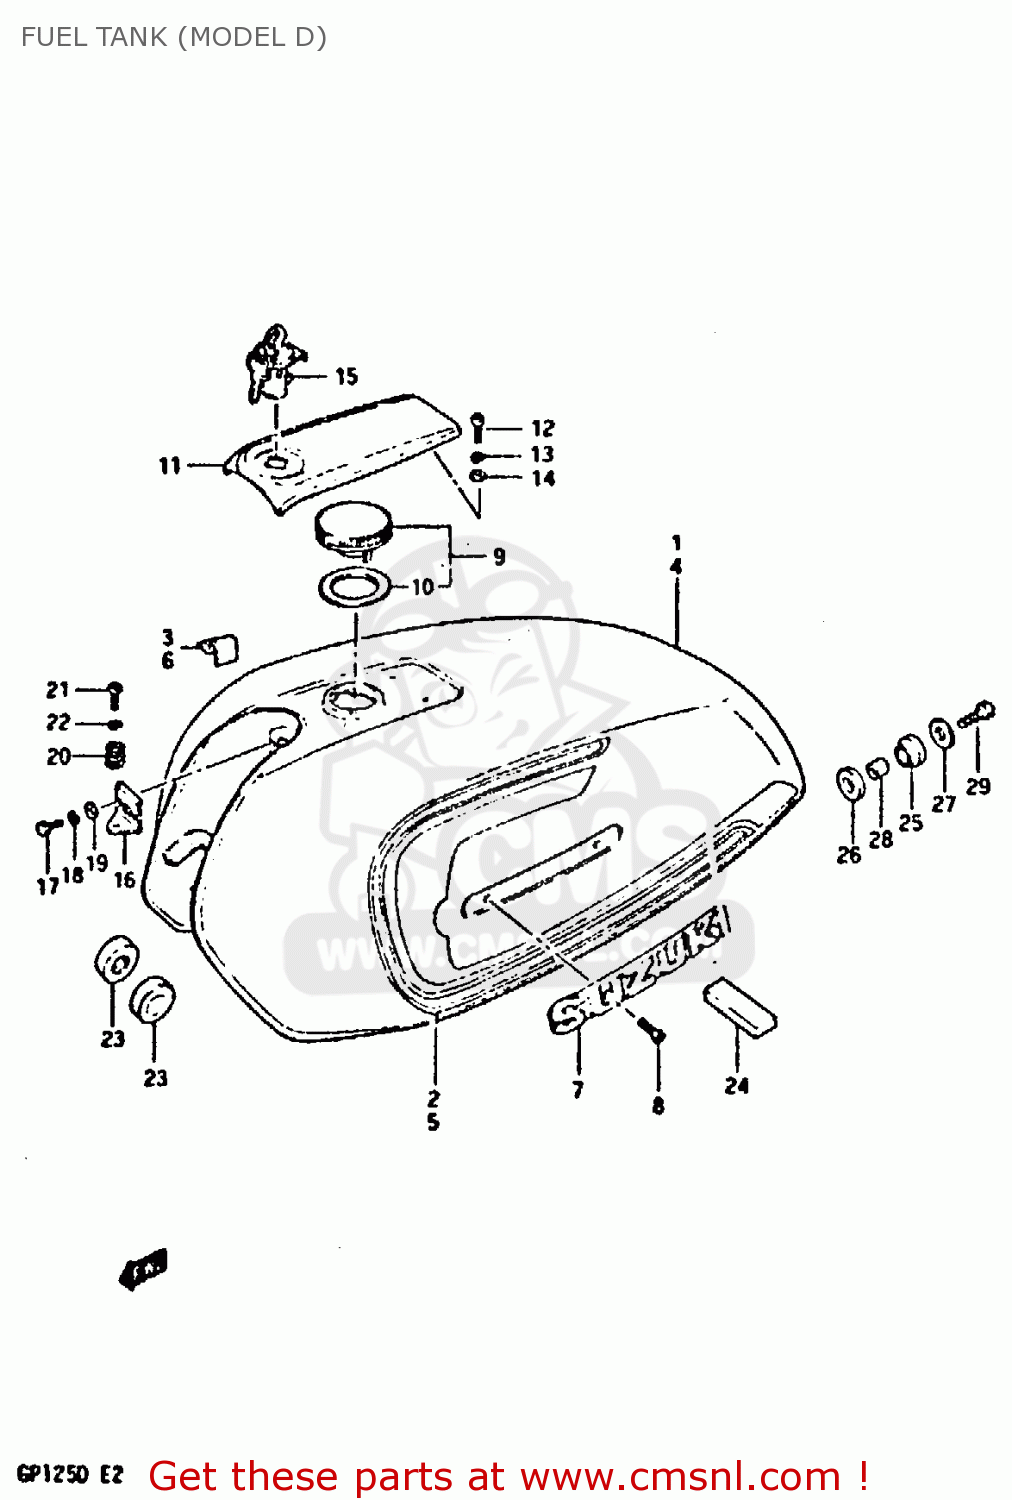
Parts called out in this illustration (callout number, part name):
1	TANK, FUEL (RED)
2	TAPE SET
3	CUSHION,FUEL TANK FR COVER
4	TANK, FUEL (BLACK)
5	TAPE SET
6	CUSHION,FUEL TANK FR COVER
7	EMBLEM
8	SCREW 3X6
9	CAP ASSY,FUEL TANK FILLER
10	GASKET (NAS)
11	COVER,FUEL TANK FR
12	BOLT
13	LOCK WASHER
14	WASHER
15	LOCK,FUEL TANK FR COVER
16	HOLDER,FUEL TANK FRONT COVER
17	BOLT
18	LOCK WASHER
19	WASHER
20	SPRING
21	SCREW
22	LOCK WASHER
23	CUSHION
24	CUSHION
25	CUSHION
26	CUSHION
27	WASHER (8.5X29X1.6)
28	SPACER (8.2X12X17)
29	BOLT (8X30)
